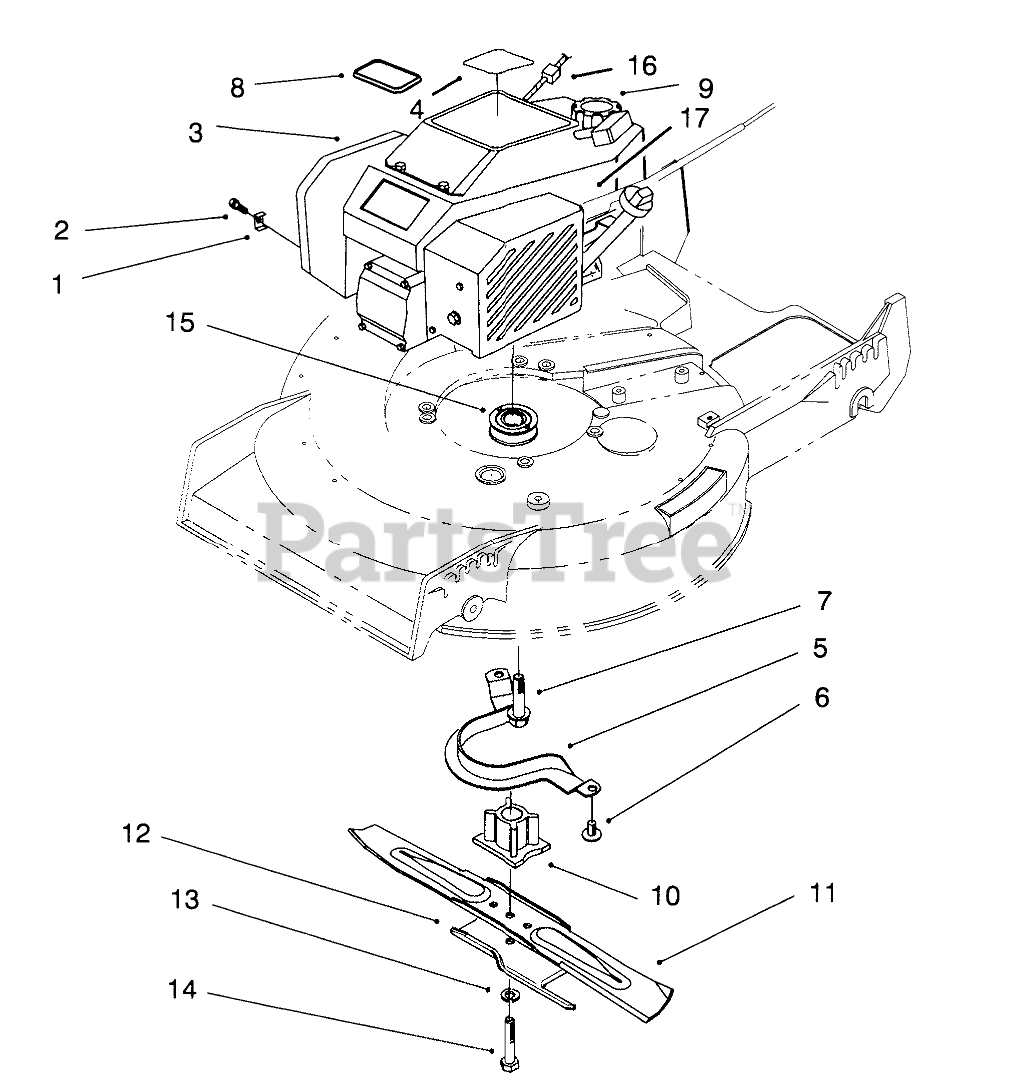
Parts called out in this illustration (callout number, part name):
1	CLAMP-CASING
2	CLAMP SCREW F/W ENGINE
3	Engine
4	DECAL - ENGINE
5	Guide-Belt
6	SCREW-HWHTF
7	SCREW-HWH
8	PLATE-LOGO
9	ASSY FUEL CAP
10	BLADE RETAINER
11	Blade
12	Accelerator
13	WASHER-LOCK
14	SCREW-BLADE
15	PULLEY-DRIVE, ZONE START
16	STOP-ROPE
17	BRAKE COVER-P/W ENGINE
